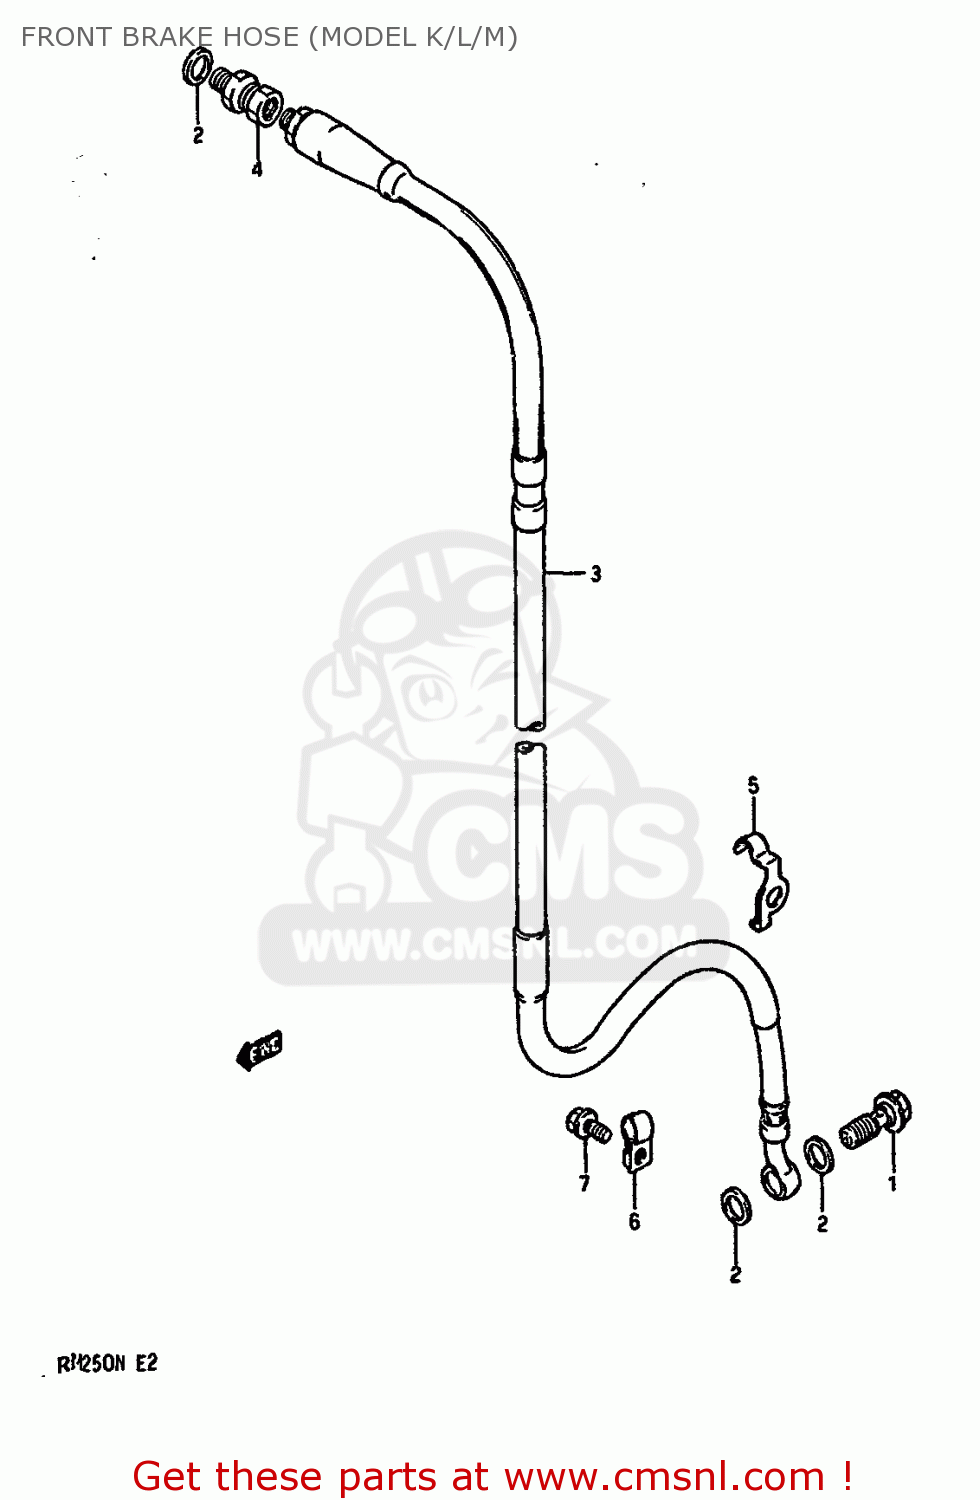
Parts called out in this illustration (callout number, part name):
1	BOLT UNION
2	WASHER(10X15X1.5)
3	HOSE,FRONT BRAKE
4	ADAPTOR,BRAKE HOSE
5	CLAMP,FRONT BRAKE HOSE
6	CLAMP,FR BRAKE HOSE NO.2
7	BOLT
